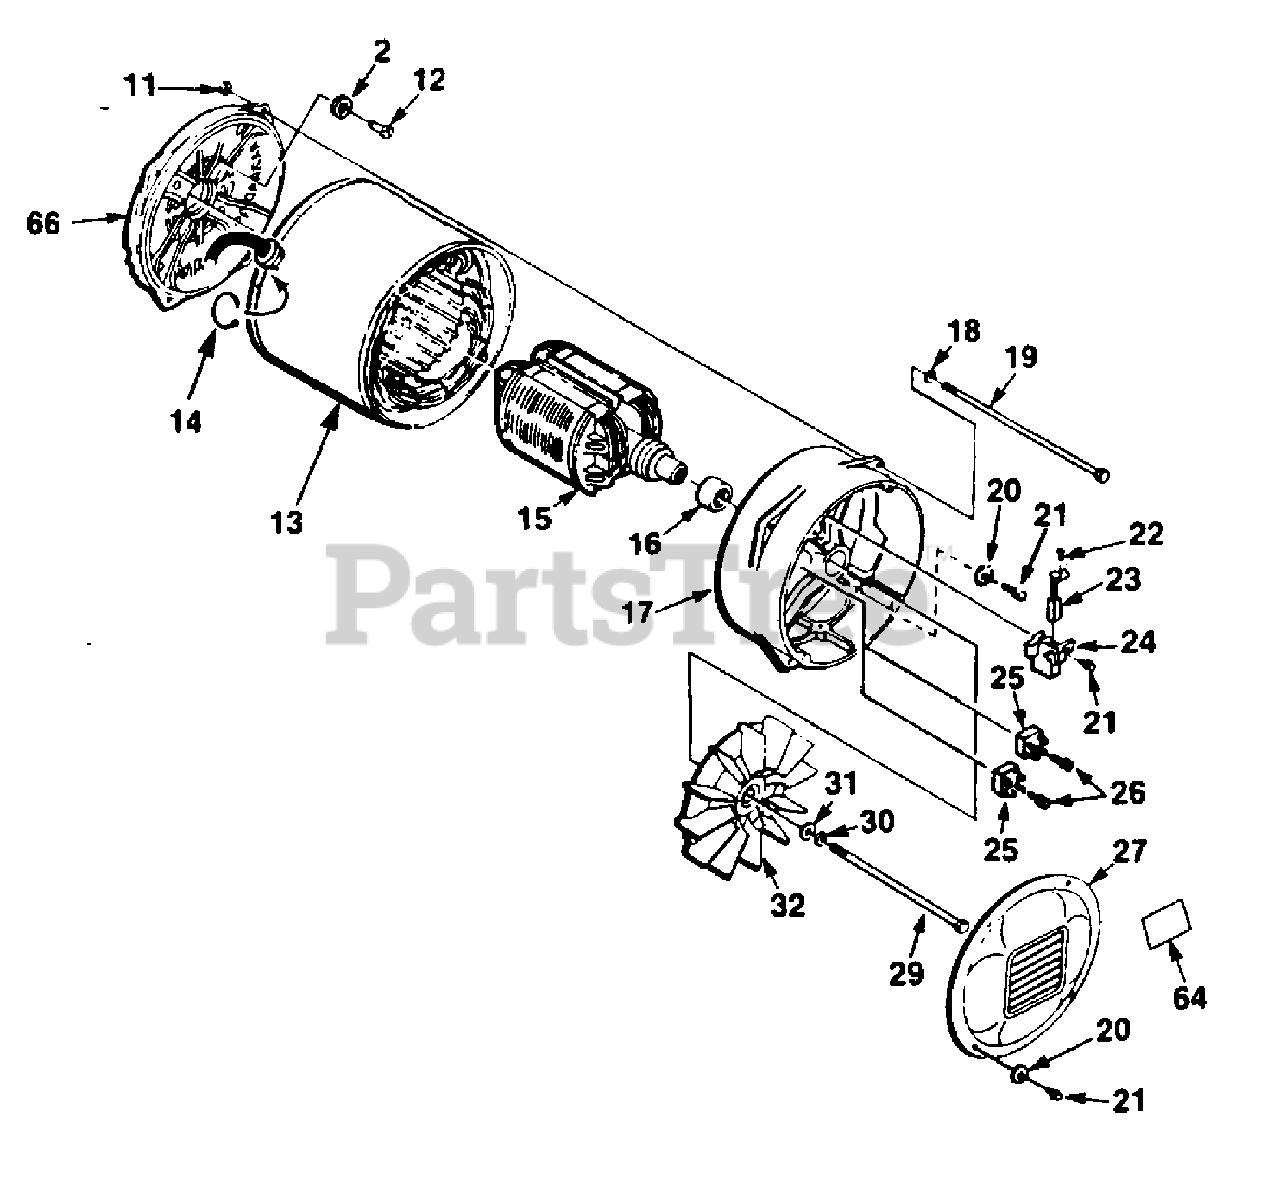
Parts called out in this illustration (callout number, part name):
2	WASHER- Lock Int.
11	NUT-Hex 1/4-20
12	SCREW-Hex hd., 5/16-24 x 3/4"
13	STATOR & SHELL
14	TIE-Cable
16	BEARING
17	BRUSH HEAD
18	WASHER-Lock
19	BOLT- Stator
20	WASHER-Lock Int. #8
21	SCREW- Thread forming
22	SCREW- Mach rd. hd. 8-32 x 3/8"
24	BRUSH HOLDER
25	RECTIFIER
26	SCREW- Hex taptite, 8-32 x 3/4"
27	COVER- Brush head
29	BOLT- Rotor .312-24 x 6 1/2"
30	WASHER- Lock 5/16"
31	WASHER-Flat 5/16"
64	DECAL- Warning
66	END BELL
